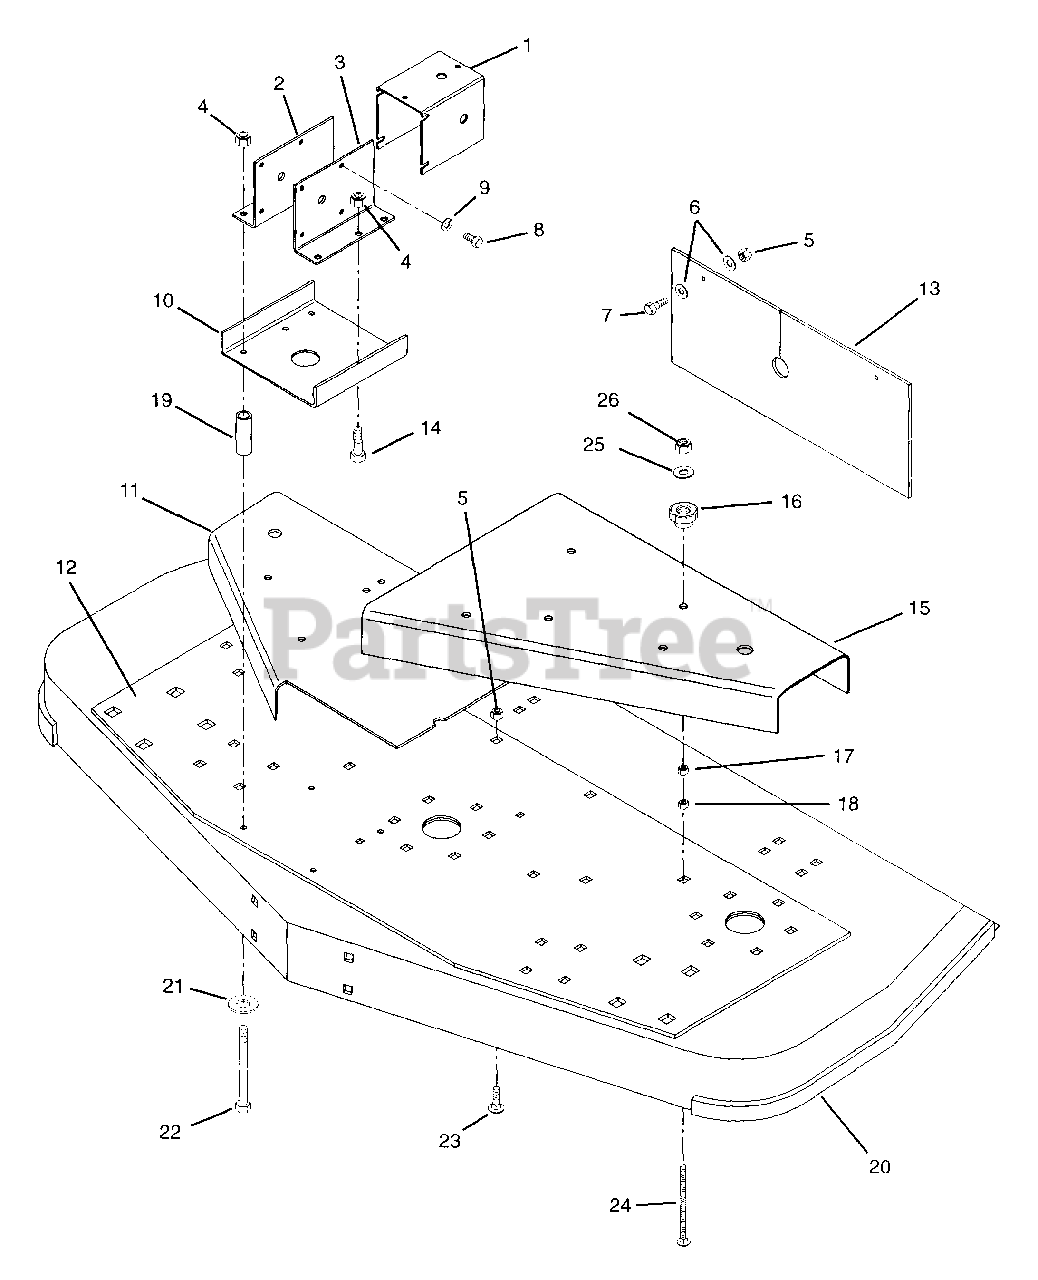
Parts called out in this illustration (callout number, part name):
1	Shield, U-Joint
2	Bracket, Gearbox Mounting Right Hand
3	Bracket, Gearbox Mounting Left Hand
4	Nut-Locking-Nylon .50-13 Grade 5
5	Nut-Locking-Nylon .375-16 Grade 2
6	Washer-Flat-Steel .406 x .812 x .065
7	Bolt-Hex .375-16 x 1.00 Grade 5
8	Bolt-Hex .380-16 x .875
9	Washer-Lock .375 x .094
10	Plate, Support
11	Cover, Belt Right Hand
12	Plate, Deck Support
13	Shield Grass
14	Bolt-Hex .50-13 x 1 Grade 5
15	Silkscreen, Belt Cover
16	Knob
17	Nut-Locking-Nylon .312-18 Grade 2
18	Nut-Jam .312-18
19	Spacer .562 x 1.00 x 2.00
20	Weldment, 72" Rear Discharge Deck
21	Washer-Flat-Steel .531 x 1.062 x .095
22	Bolt-Hex .50-13 x 3.75
23	Bolt-Round Head Square Neck .38-16 x 1.0
24	Bolt-Round Head Square Neck .31-18 x 4.0
25	Washer-Flat-Steel .323 x .625 x .062
26	Nut-Locking-Nylon .312-18 w/ Insr Grade 2
